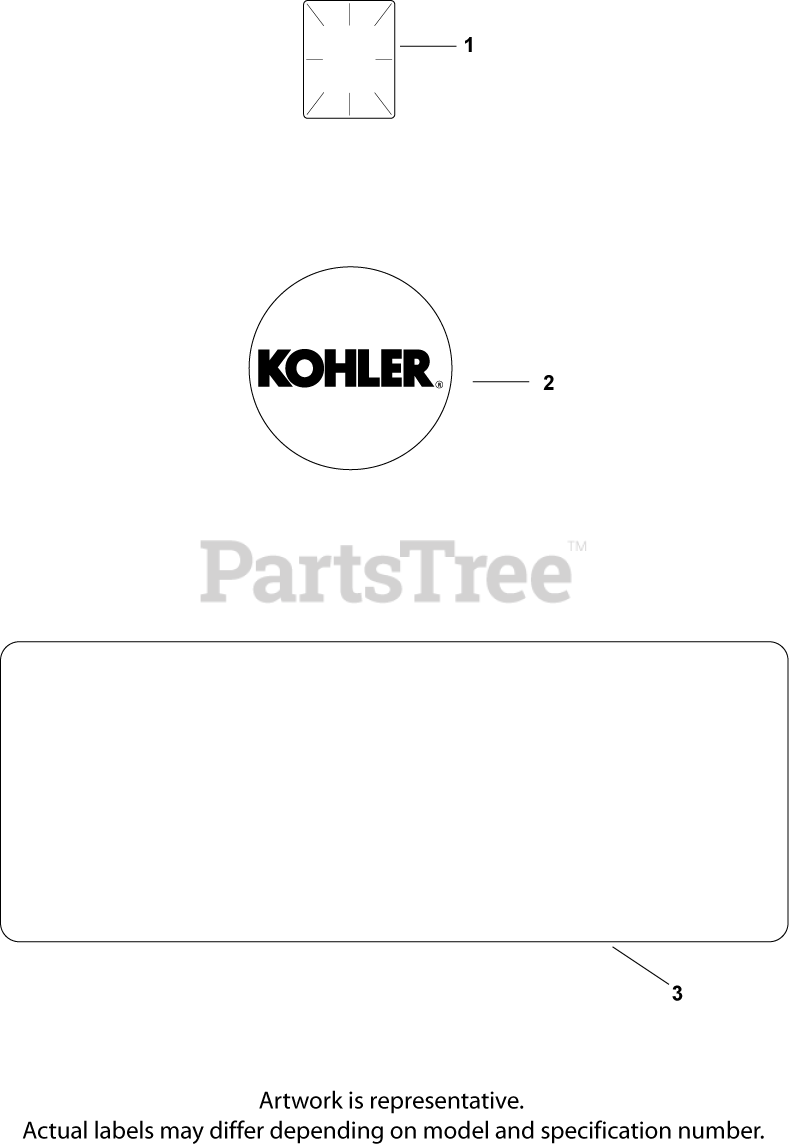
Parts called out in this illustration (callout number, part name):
1	DECAL, CLEAR LAMINATE USE 25 113 70-S
2	DECAL, GRASS SCREEN USE 24 113 499-S
3	DECAL, 22 HP
